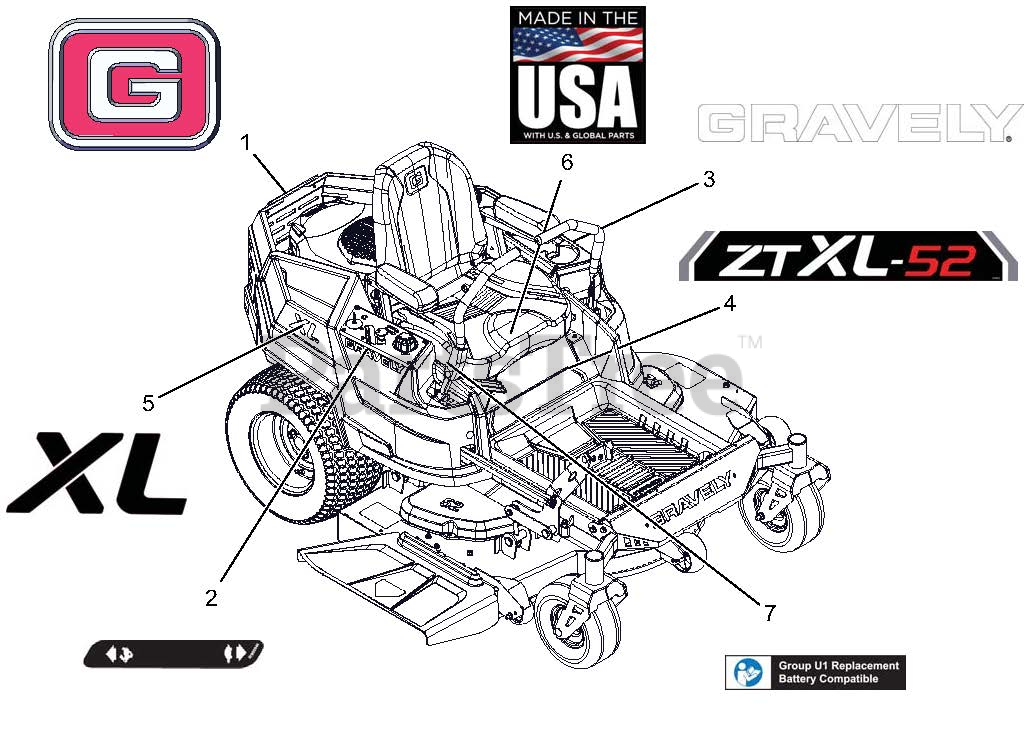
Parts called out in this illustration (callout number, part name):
1	DECAL, GRAVELY BRAND
2	DECAL, DASH DECAL
3	DECAL, 9.5" GRAVELY LOGO
4	DECAL, ZT XL 52"
5	DECAL, "XL"
6	DECAL, MADE IN USA
7	DECAL, U1 BATTERY REPLACEMENT
